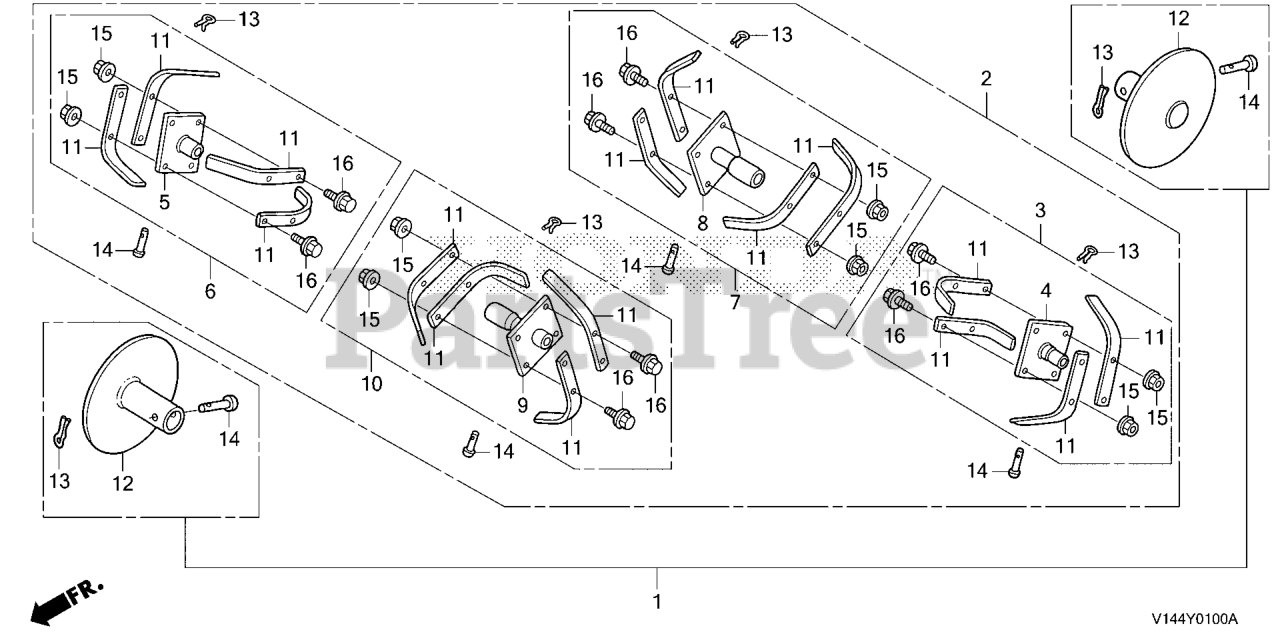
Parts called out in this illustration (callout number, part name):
1	DISK KIT, SIDE
2	ROTOR KIT *NH1* (BLACK)
3	PIPE, L. MAIN *NH1* (BLACK)
4	PIPE, L. ROTOR MAIN
5	PIPE, R. ROTOR MAIN
6	PIPE, R. MAIN *NH1* (BLACK)
7	PIPE, L. EXTENSION *NH1* (BLACK)
8	PIPE, L. ROTOR EXTENSION
9	PIPE, R. ROTOR EXTENSION
10	PIPE, R. EXTENSION *NH1* (BLACK)
11	TINE A, ROTOR
12	DISK, SIDE
13	PIN, SNAP (7MM)
14	PIN, WHEEL (8X35)
15	NUT, FLANGE (8MM)
16	BOLT, FLANGE (8X18) Use from Frame SN 1256673.
